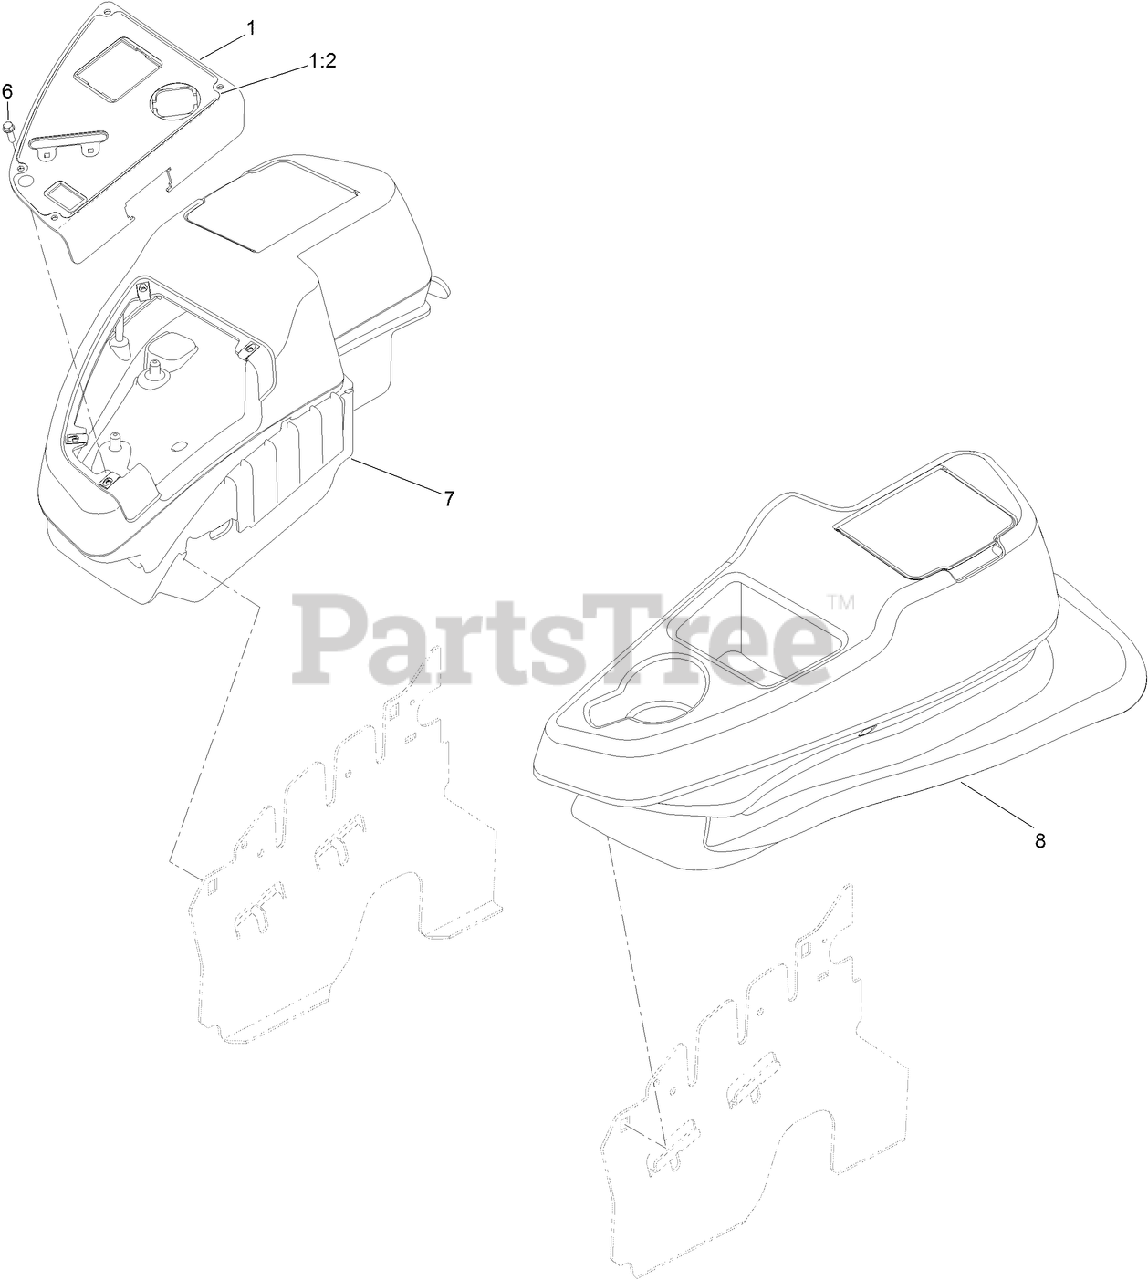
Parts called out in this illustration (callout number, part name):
1	CONTROL PANEL W/DECAL
1:2	DECAL, CONTROL PANEL
6	SCREW-HWH
7	RH CONSOLE ASM
8	LH CONSOLE ASM
